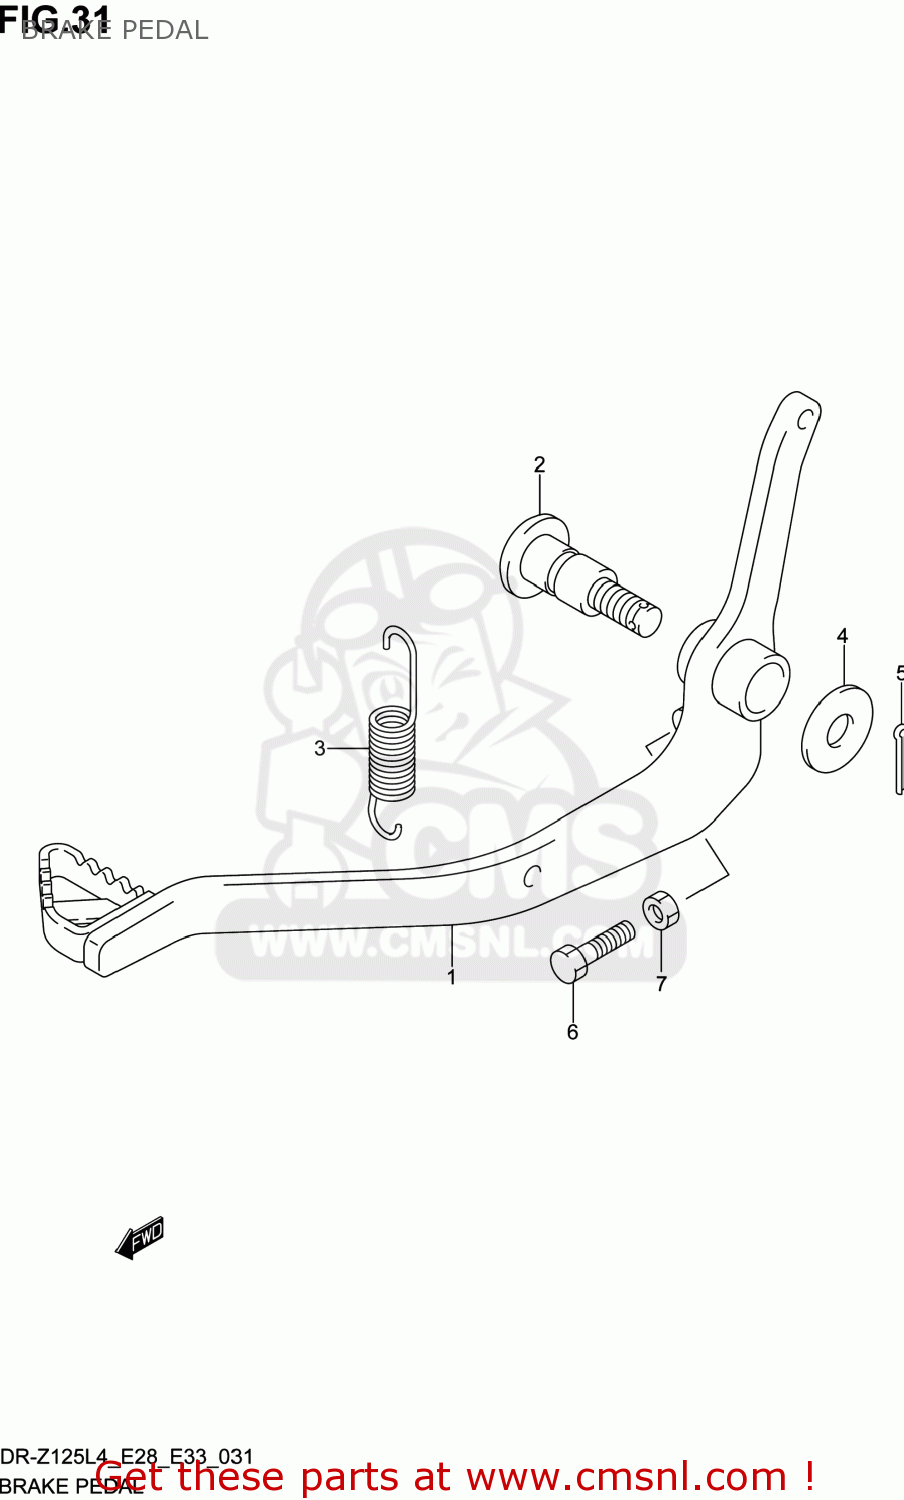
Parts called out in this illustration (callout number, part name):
1	PEDAL,BRAKE
2	SHAFT,BRAKE PEDAL
3	SPRING
4	WASHER
5	PIN
6	BOLT(6X18)
7	NUT
